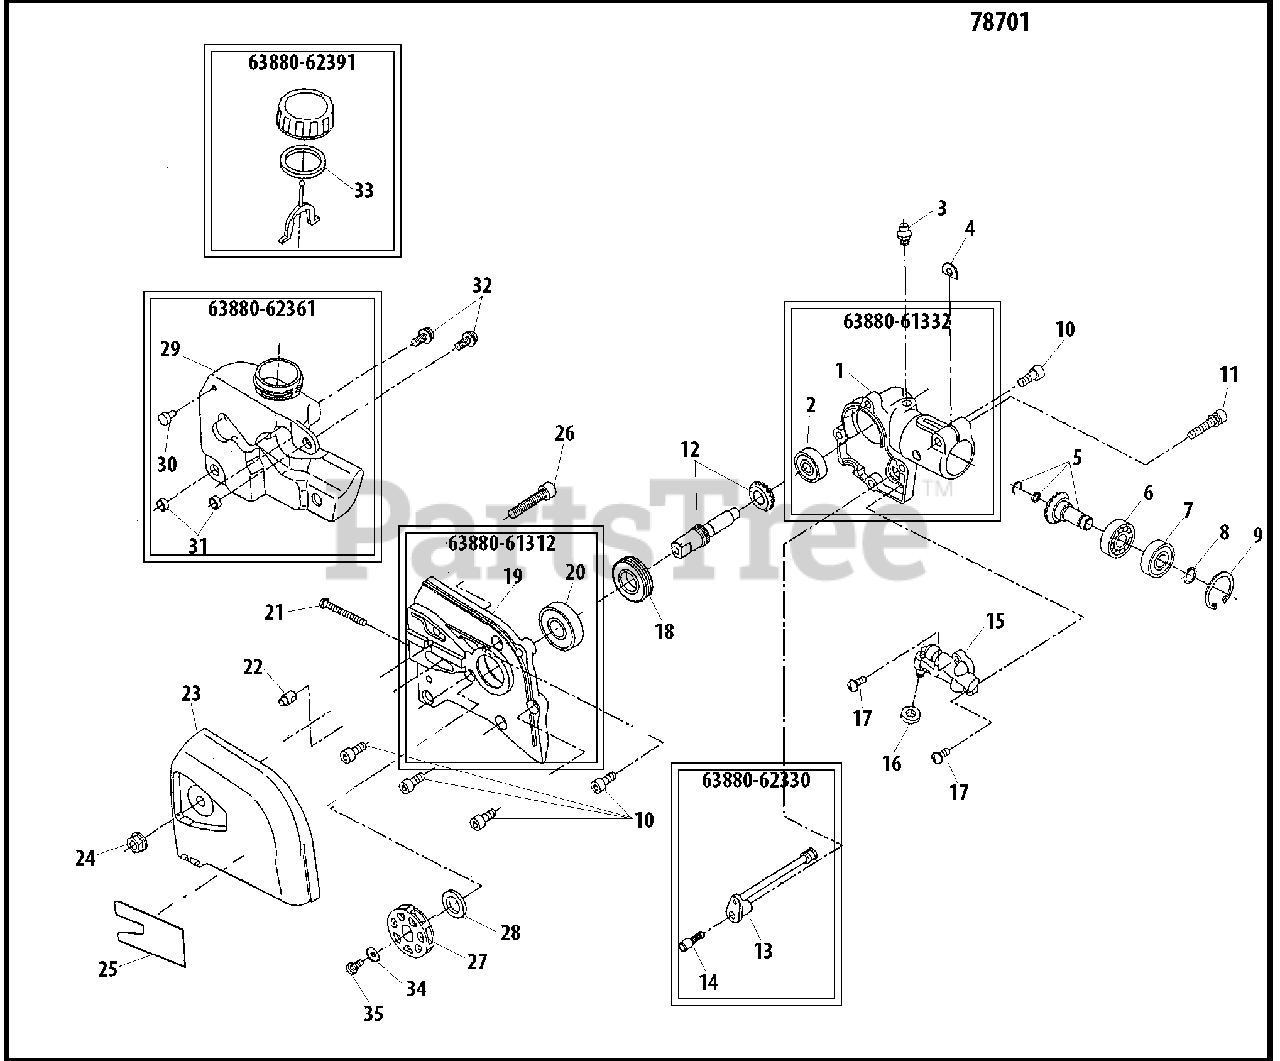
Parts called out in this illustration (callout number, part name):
1	CASE, GEAR - RIGHT
2	BEARING, BALL - 627ZZ
3	FITTING, GREASE
4	SHIM
5	GEAR - BEVEL
6	BEARING, BALL - 609
7	BEARING, BALL - 609ZZ
8	RING, RETAINING
9	RING, RETAINING - 24
10	SCREW - 5X12
11	SCREW - 5X25
12	GEAR - SHAFT
13	PIPE - OIL
14	FILTER
15	AUTO-OILER ASSY
16	GASKET, PUMP
17	SCREW - 4X10
18	GEAR - WORM
19	GEAR CASE ASSY - LEFT
20	BEARING, BALL - 6001DDU
21	SCREW - 4X35
22	TENSIONER, CHAIN
23	COVER
24	NUT - 6 -- FLANGE
25	LABEL - CAUTION
26	SCREW - 6X30
27	SPROCKET
28	COLLAR
29	TANK, OIL
30	VALVE, OIL
32	SCREW - 5X12
33	GASKET, CAP
34	WASHER - 6
35	SCREW - 6X14
